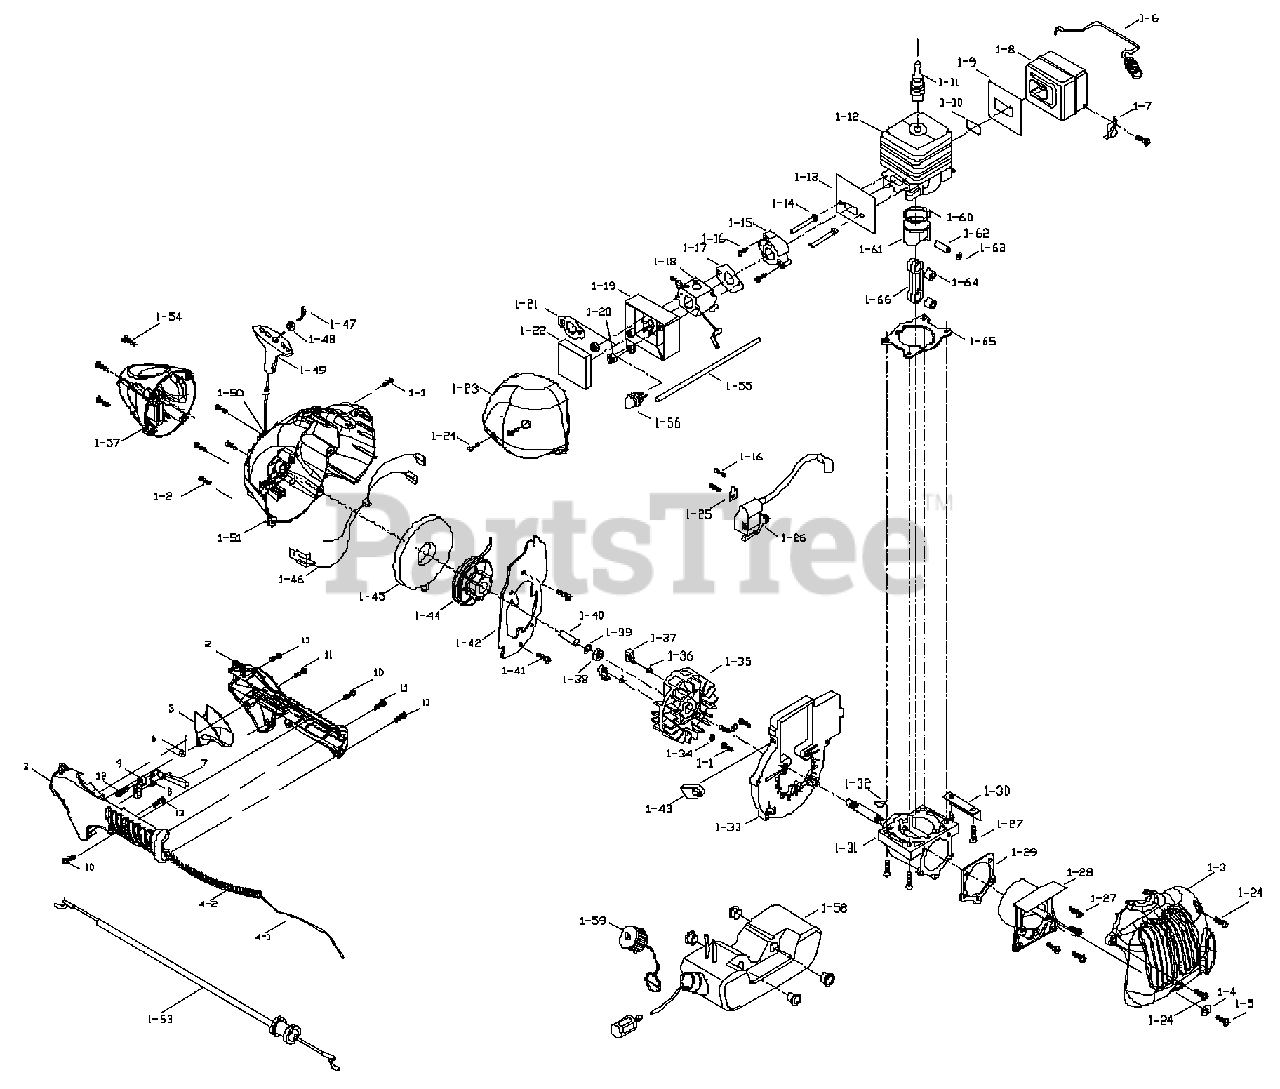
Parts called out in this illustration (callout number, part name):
1-2	WASHER, PLASTIC
1-6	SPRING, MUFFLER
1-8	KIT, MUFFLER
1-9	GASKET, MUFFLER
1-11	SPARK PLUG
1-13	GASKET,MANIFOLD
1-14	SCREW
1-15	MANIFOLD, CARBURETOR
1-17	GASKET, CARBURETOR
1-18	CARBURETOR ASS'Y
1-21	TERMINAL TAB
1-22	FILTER, AIR
1-23	COVER, AIR CLEANER
1-25	TERMINAL TAB
1-26	IGNITION ASSEMBLY
1-30	SHIELD, MUFFLER
1-31	SHIELD, MUFFLER
1-32	KEY, FLYWHEEL
1-40	KIT, SPACER, CLUTCH
1-42	RETAINER, PULLEY
1-44	PULLEY, STARTER
1-45	PACKAGE, SPRING ASS'Y
1-46	WIRE ASS'Y, SWITCH
1-47	ROPE, STARTER
1-48	WASHER, NYLON
1-49	HANDLE, STARTER
1-50	GUIDE, ROPE
1-51	HOUSING 116C YELLOW
1-53	THROTTLE CABLE
1-54	SCREW
1-57	HOUSING, CLUTCH
1-58	TANK ASS'Y FUEL
1-59	CAP ASS'Y FUEL TANK
1-60	RING, PISTON
1-65	GASKET, CYLINDER
2	HOUSING HANDLE
3	HOUSING HANDLE
4-1	THROTTLE CABLE
7	LIBERATE SHAFT
9	LIBERATE CHUNK
